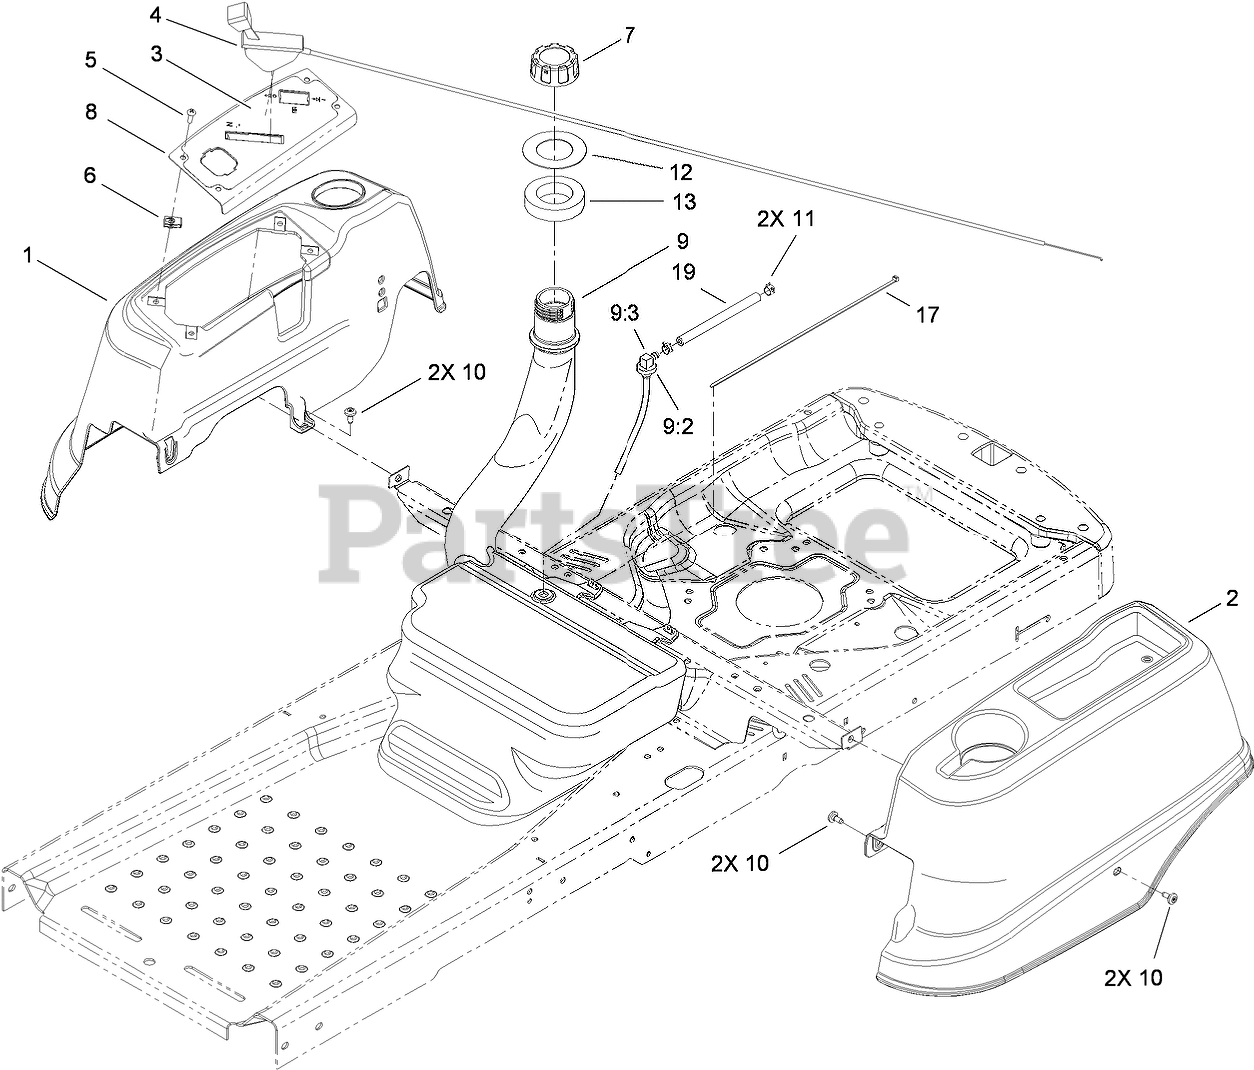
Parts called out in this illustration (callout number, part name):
1	POD-RH
2	POD-LH
3	DECAL-PANEL, CONTROL
4	CABLE-THROTTLE
5	SCREW-PRH
7	CAP-GAS
8	PANEL-CONTROL
9	FUEL TANK ASM
9:2	BUSHING
9:3	FITTING-90 DEGREE
10	SCREW-SHOULDER
11	CLAMP-HOSE
12	WASHER-RUBBER
13	SEAL-FOAM
17	TIE-CABLE
19	HOSE-FUEL
